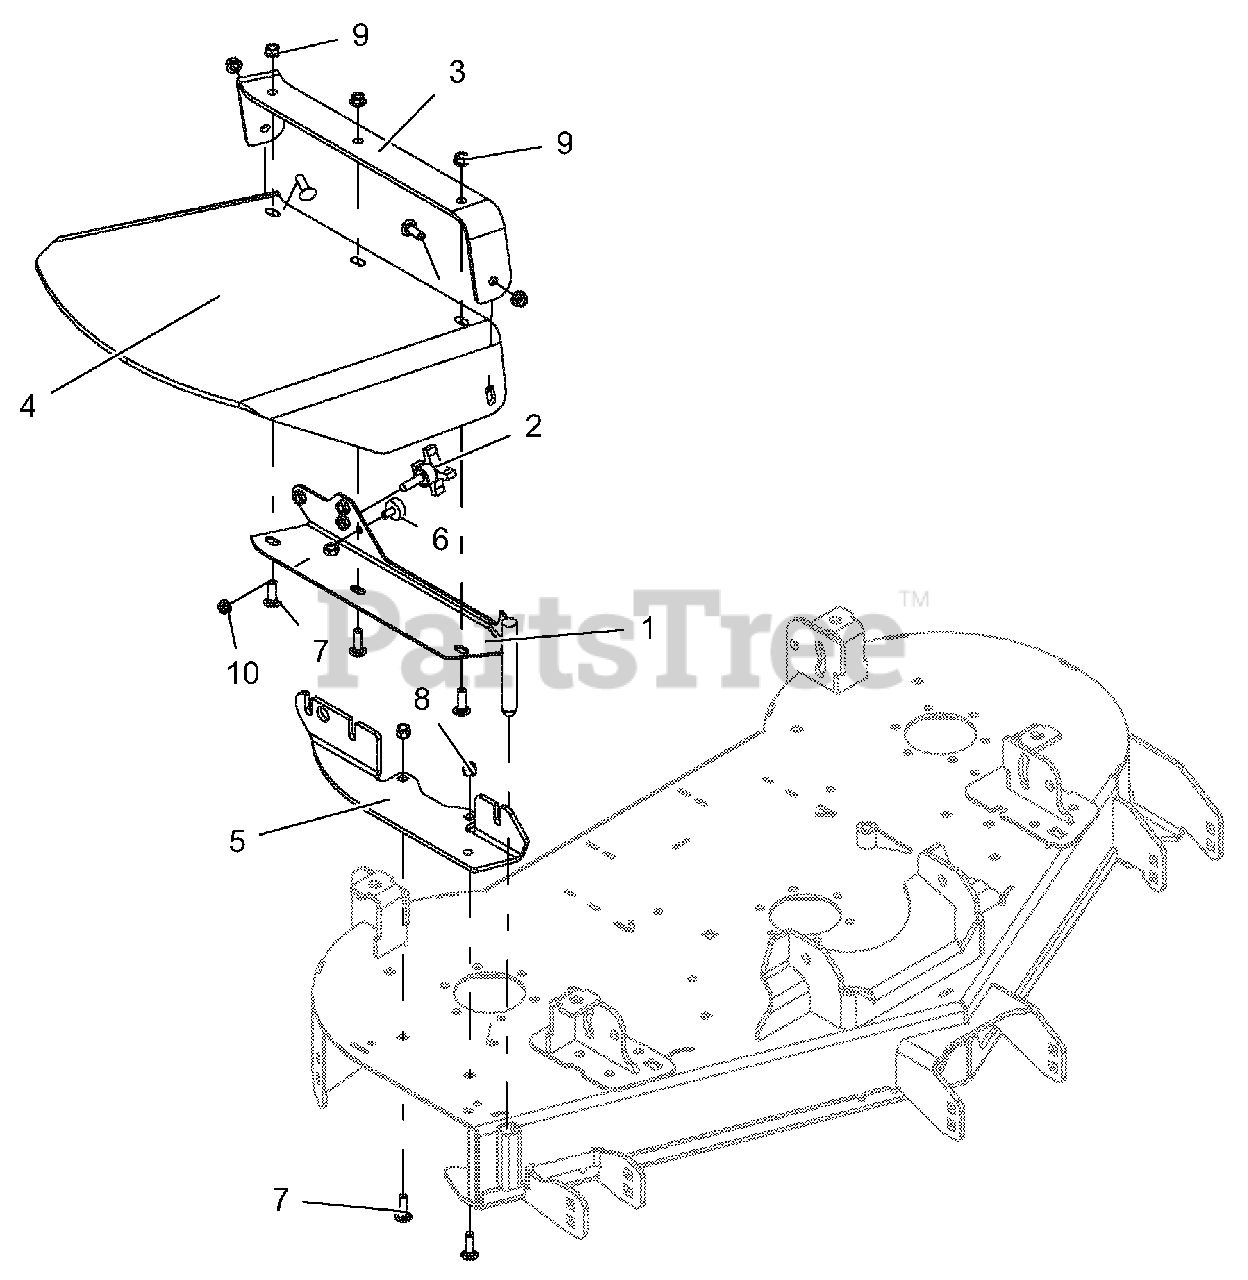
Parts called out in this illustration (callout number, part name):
1	WLDT. DISCHARGE - R ED
2	KNOB, 3/8 x 1.25 - 4 PRONG
3	STRAP, WALK RUBBER DISCHARGE - RED
4	SHIELD, WALK RUBBER DISCHARGE
5	BRKT, DISCHARGE 48 - RED
6	BUMPER, RUBBER
7	BLT-RDHDSQNK .38-16 x 1.25 G5 YWZC
8	NUT-LK-NYL .38-16 YWZC
9	@NUT-SPNLK-FLG .375-16 YWZC
10	@NUT-SPNLK-FLG .312-18 YWZC
